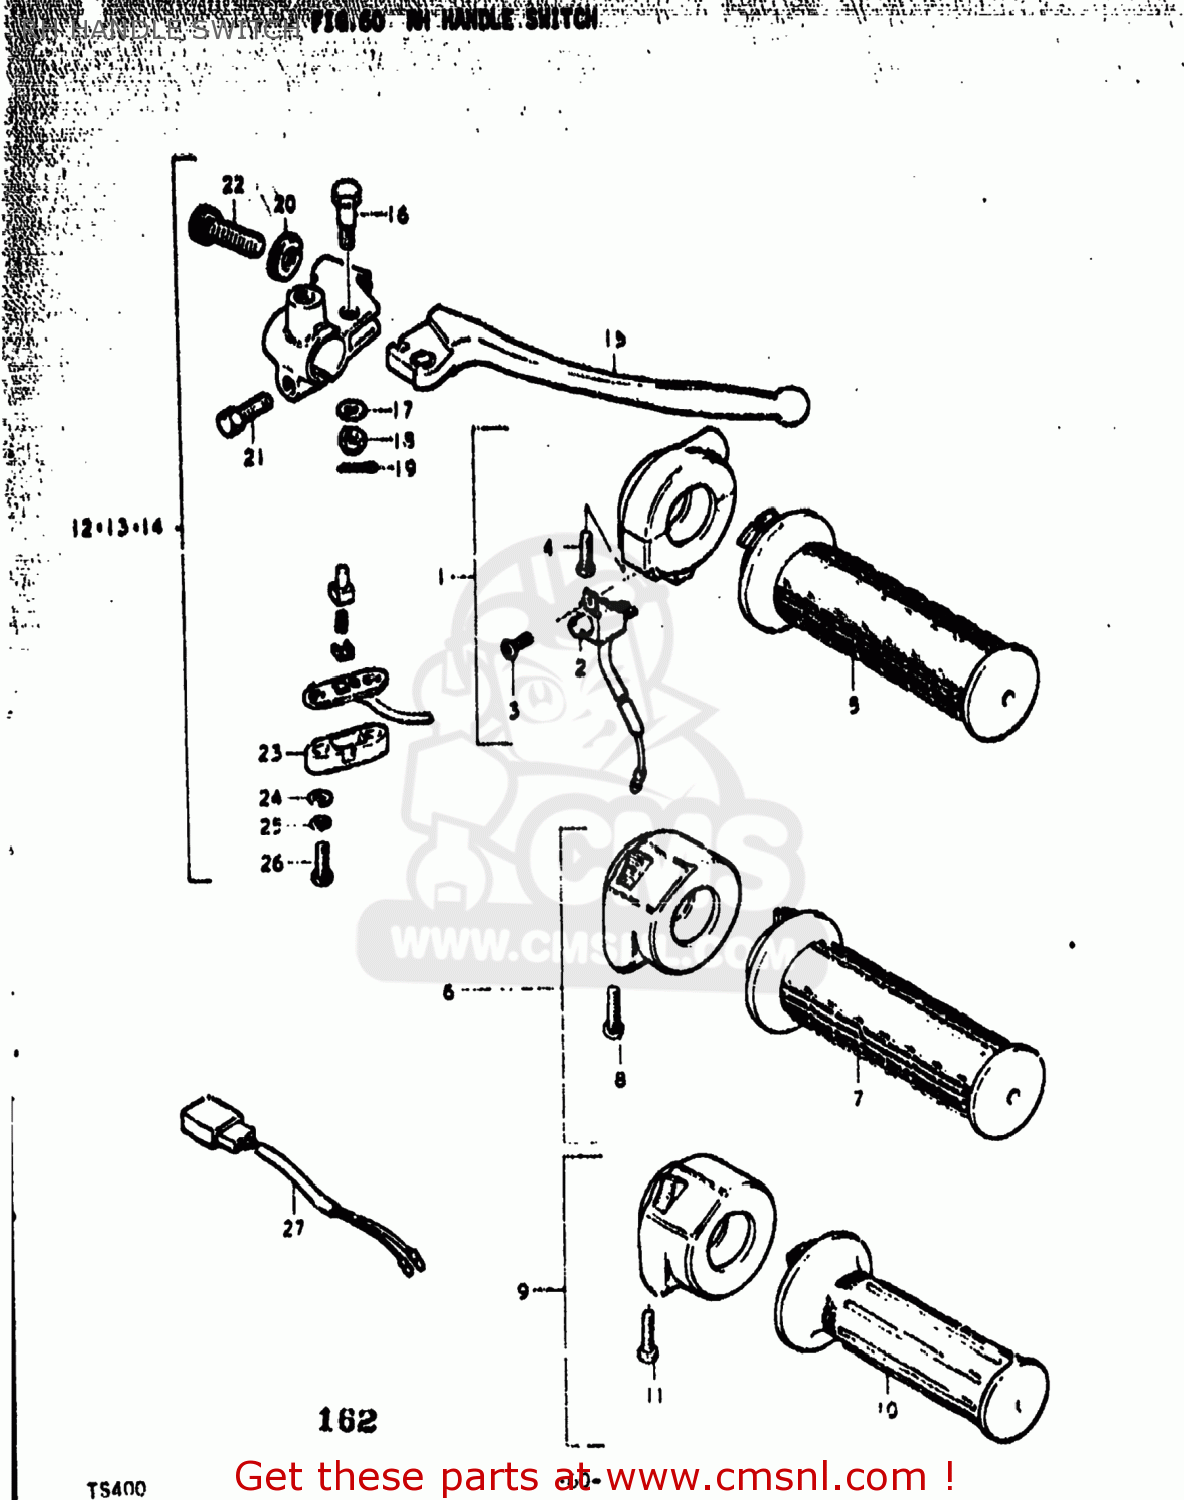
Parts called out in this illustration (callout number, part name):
1	GRIP ASSEMBLY,THROTTLE
3	SCREW
4	SCREW
5	GRIP,THROTTLE
6	GRIP ASSEMBLY,THROTTLE
7	GRIP,THROTTLE
8	SCREW
9	GRIP ASSEMBLY,THROTTLE
10	GRIP,THROTTLE
11	SCREW
12	LEVER ASSEMBLY,BRAKE
13	LEVER ASSEMBLY,BRAKE
14	LEVER ASSEMBLY,BRAKE
15	LEVER ASSEMBLY,ADJUST
16	BOLT,LEVER
17	LOCK WASHER
18	NUT,LEVER FITTNG
19	COTTER PIN
20	NUT,CABLE ADJUSTER
21	BOLT
22	ADJUSTER,CABLE
23	COVER,FR BK TERMINAL BASE
24	WASHER
25	LOCK WASHER
26	SCREW
27	LEAD WIRE
